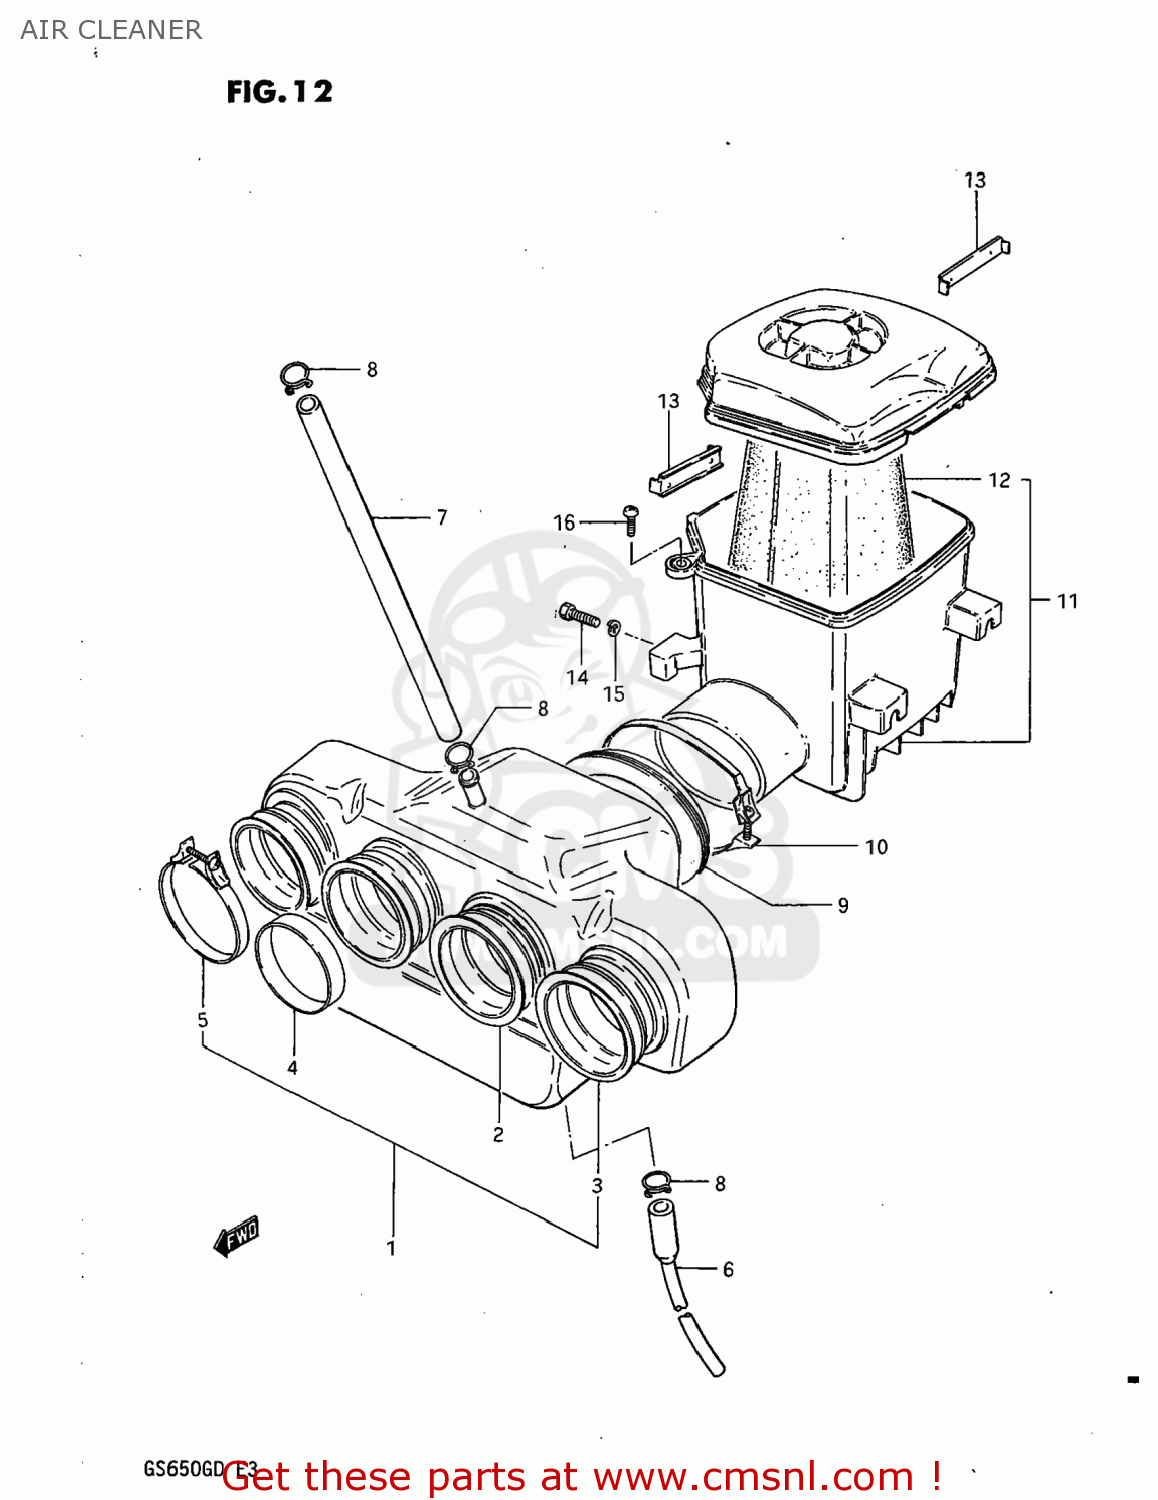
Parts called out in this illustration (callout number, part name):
1	CASE,AIR CLEANER,FRONT
2	TUBE,OUTLET,INNER
3	TUBE,OUTLET OUTER
4	RING,CARBURETOR AIR INLET HOSE
5	CLAMP
6	DRAIN TUBE
7	HOSE
8	CLIP
9	JOINT,HOSE AIR CLEANER
10	CLAMP
11	CLEANER SET,AIR,REAR
12	FILTER ASSY
13	SLIDER
14	BOLT, UPPER
15	LOCK WASHER
16	SCREW
